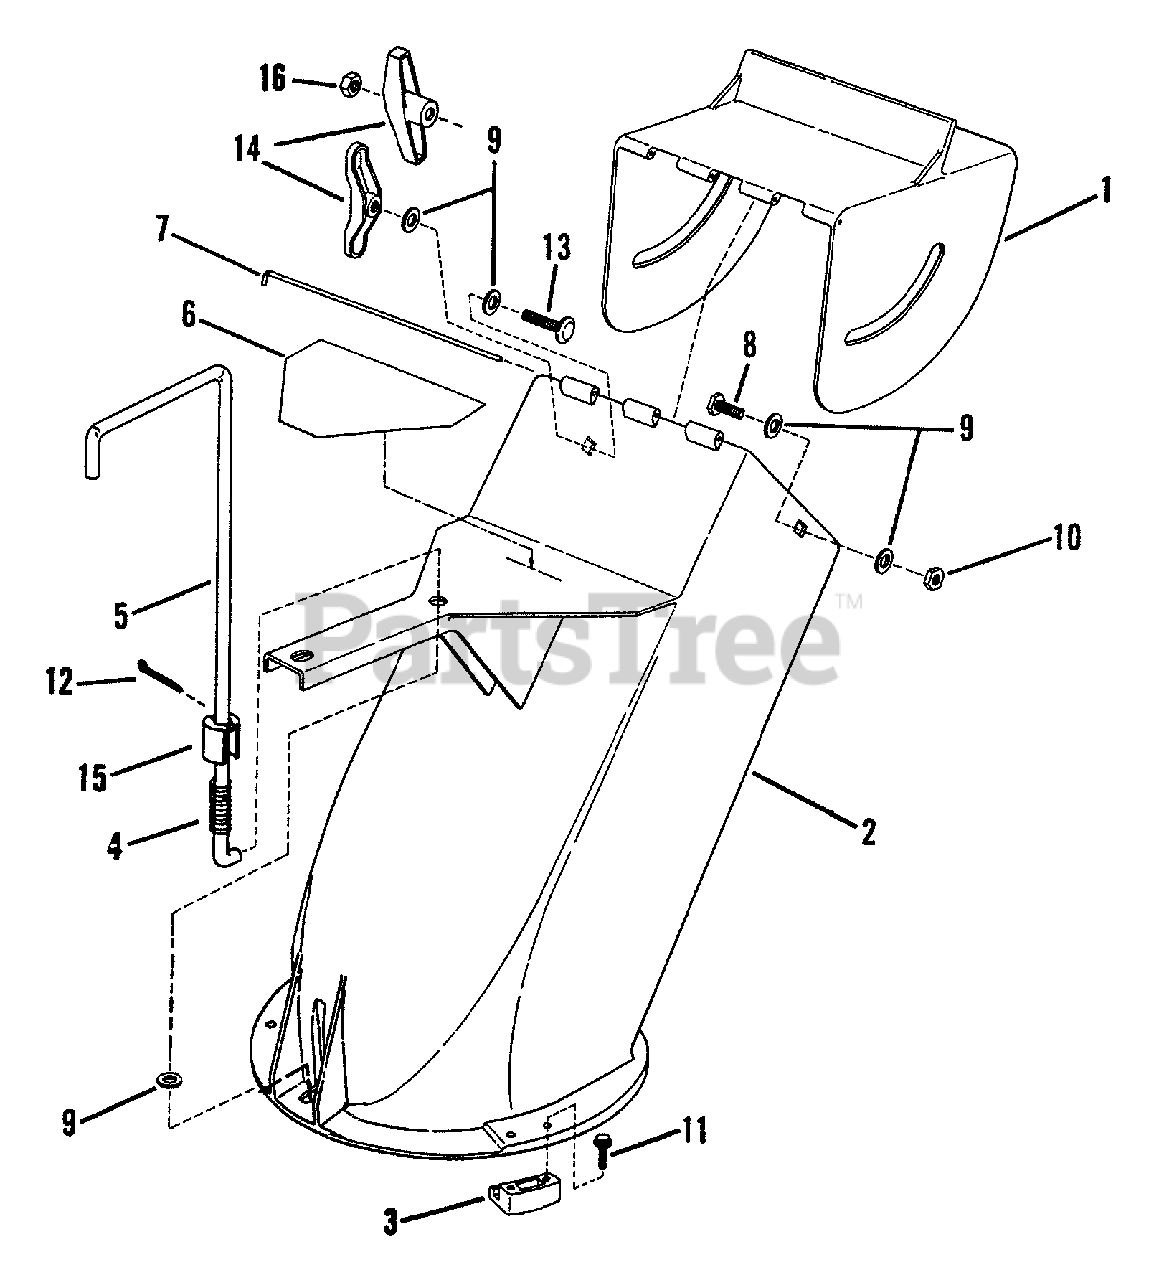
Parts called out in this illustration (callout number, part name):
1	DEFLECTOR, Discharge
2	ASSEMBLY, Chute & Discharge Decal
3	RETAINER, Chute to Housing
4	SPRING, Release Rod
5	ROD, Release
6	DECAL, Chute Danger
7	PIN, Wire Hinge
8	SCREW, 5/16-24 x 1" Hex Head Cap, Grade 5
9	WASHER, 5/16 Flat
10	NUT, 5/16-24 Hex Center Lock
11	SCREW, #10-24 x 5/8" Hex Washer Face Self-Tap
12	PIN, 3/32 x 3/4" Cotter
13	BOLT, 5/16-18 x 1" Square Neck Carriage, Grade 5
14	NUT, 5/16-18 Wing
15	STOP, Handle
16	NUT, 5/16-18 Hex, Grade 5
